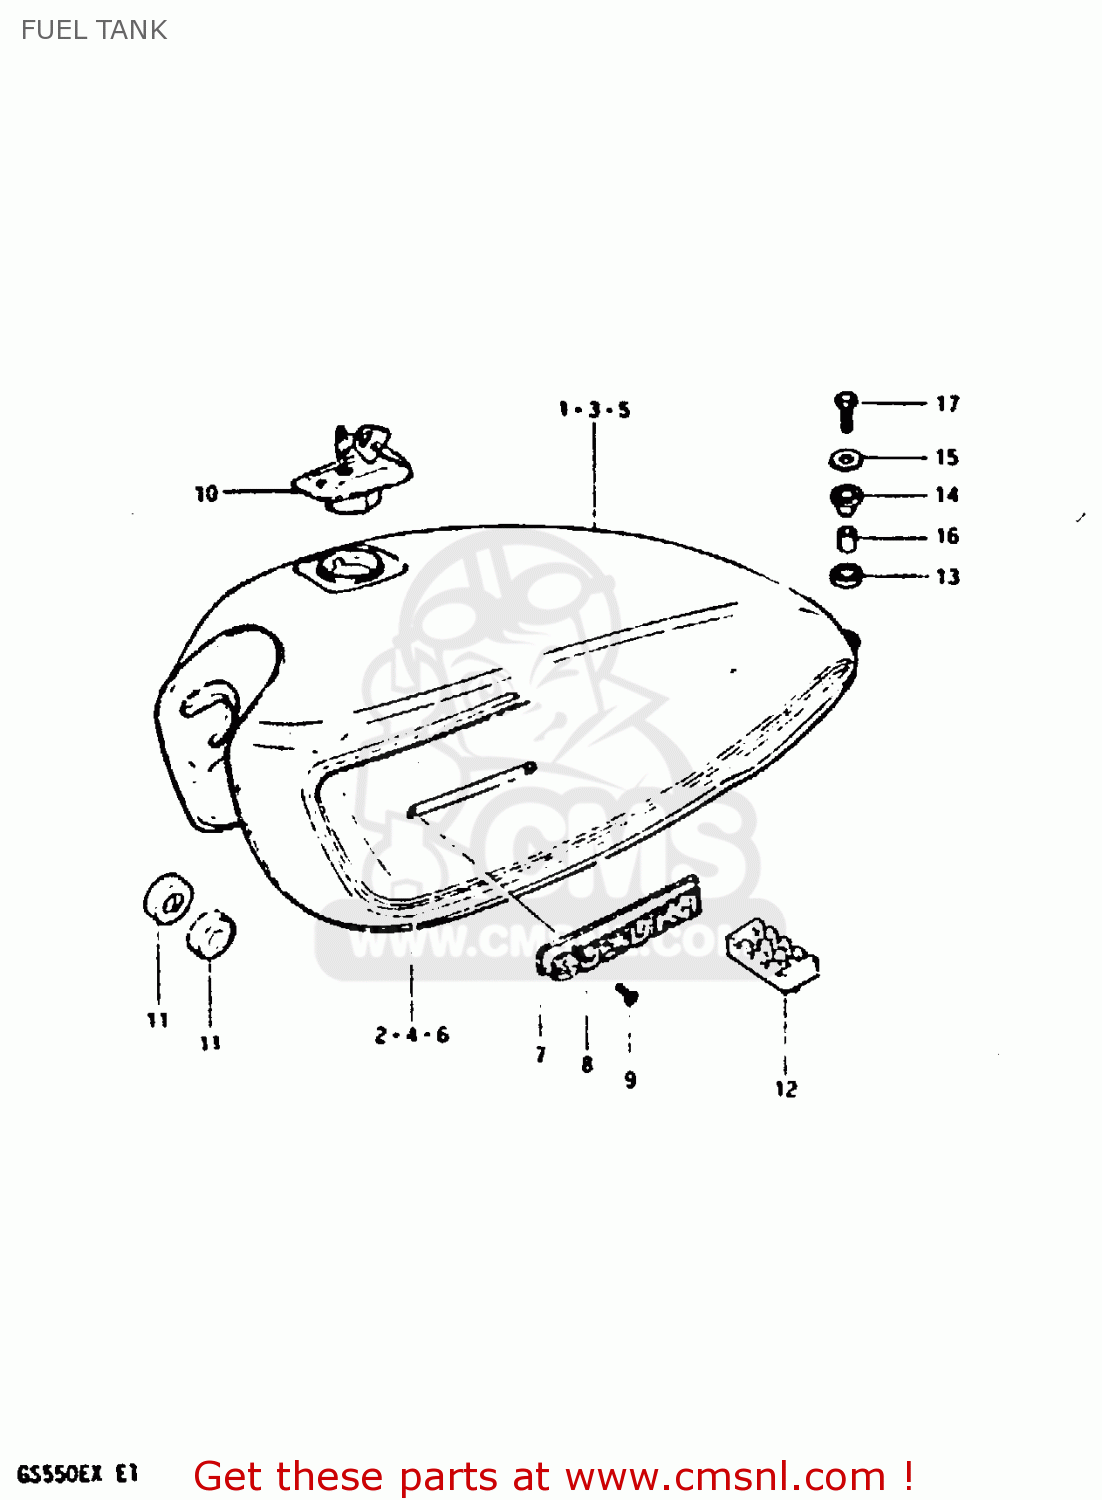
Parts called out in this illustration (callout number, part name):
1	TANK, FUEL (BLACK)
2	TAPE SET
3	TANK, FUEL (RED)
4	TAPE SET
5	TANK, FUEL (BLUE)
6	TAPE SET
8	EMBLEM,FUEL TANK
9	SCREW 3X6
10	CAP SET,FUEL TANK
11	CUSHION
12	CUSHION,FUEL TANK CTR
13	CUSHION
14	CUSHION
15	WASHER (6.5X24X1.6)
16	SPACER
17	BOLT
